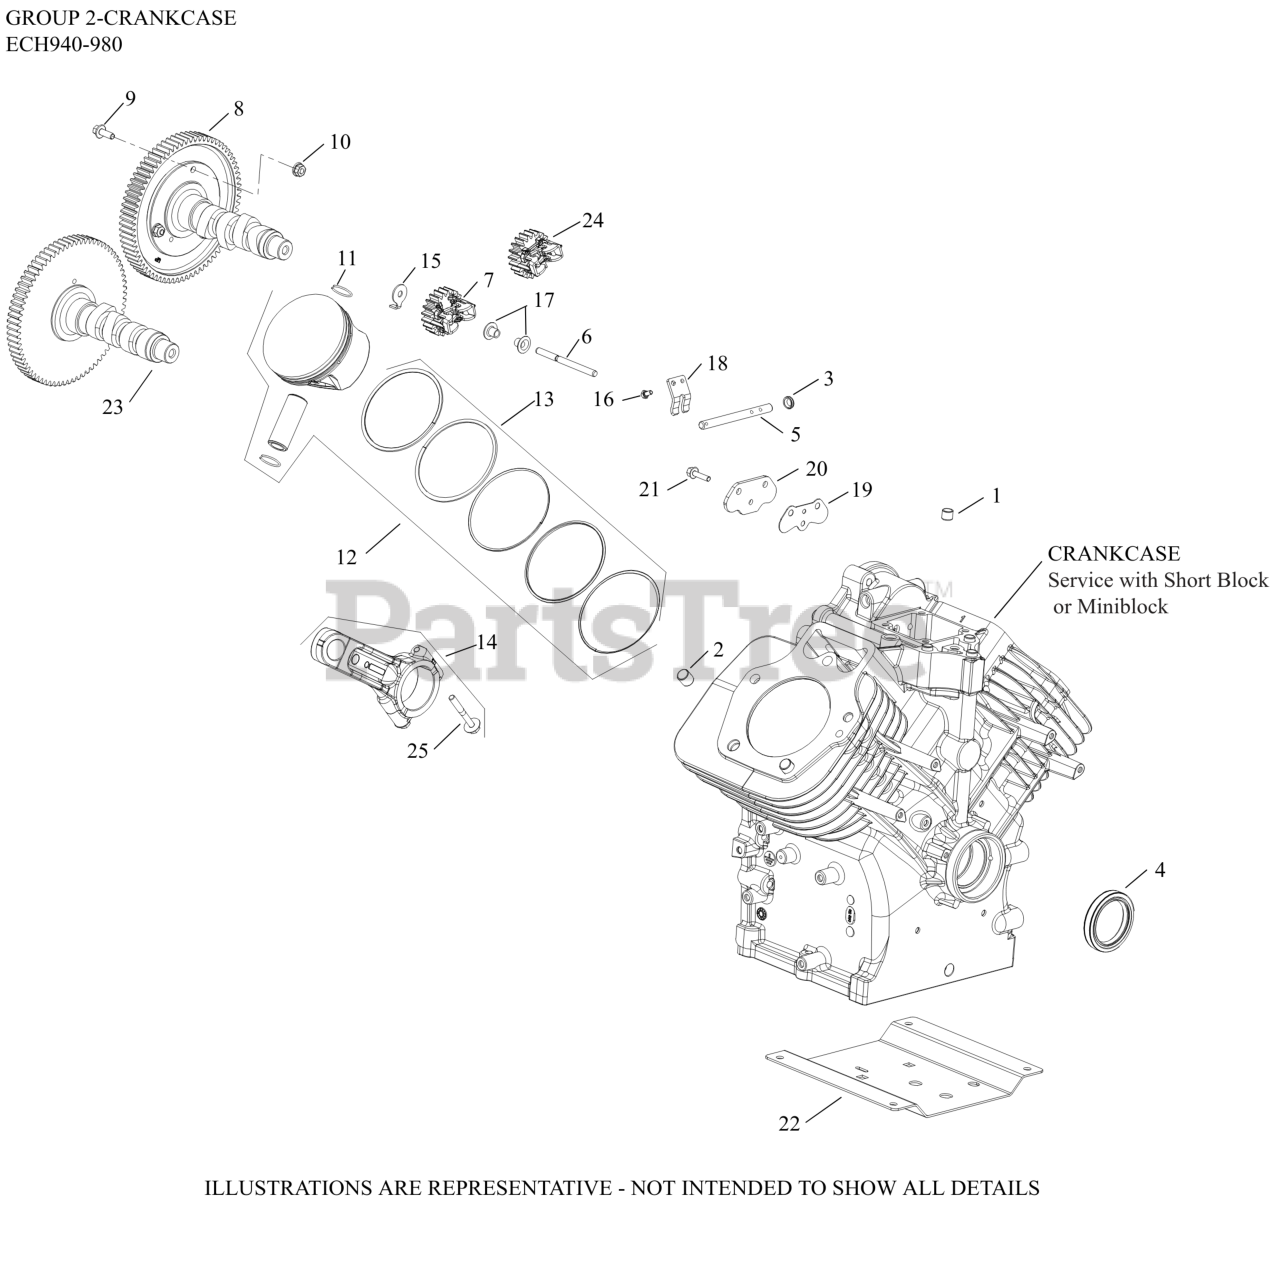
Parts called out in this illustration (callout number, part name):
2	PIN, LOCATING
3	SEAL, GOVERNOR CROSS SHAFT
4	SEAL, OIL
5	SHAFT, GOVERNOR CROSS
6	SHAFT, GOVERNOR GEAR
8	KIT, CAMSHAFT-USE 62 010 12-S
9	SCREW,HEX FLNGE
10	NUT, FLG M6X1.0
11	RETAINER, PISTON PIN
12	RING, SET PISTON (STD)
13	KIT, PISTON (STD)
13	KIT, PISTON (0.25 OS)
13	KIT, PISTON (0.50 OS)
14	CONNECTING ROD ASSEMBLY
15	TAB, LOCKING
16	SCREW, HEX HEAD
17	PIN, GOVERNOR REGULATING
18	YOKE, GOVERNOR
19	GASKET, LIFTER FEED COVER
20	KIT, COVER, LIFTER FEED
21	SCREW, HVY FLG M5X0.8X20
24	KIT, GOVERNOR GEAR
25	KIT, ROD BOLTS
